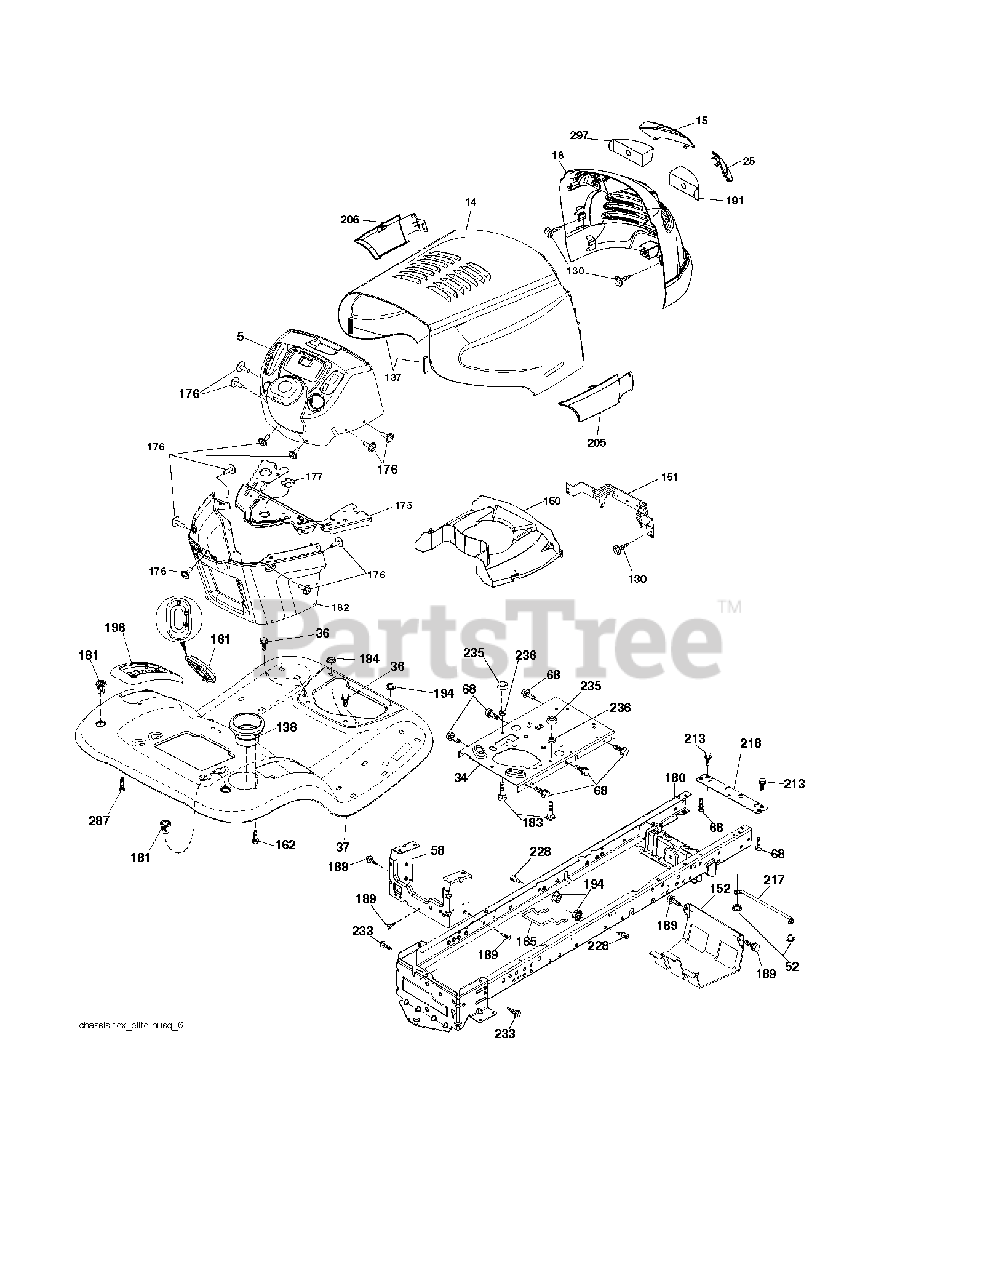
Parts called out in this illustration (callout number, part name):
14	HOOD.PNT.ELITE.TVENT.SVENT.SSK
18	GRILLE.ELITE HUSQ.BLACK.DL.
34	PLATE.ENGINE.WELDED.CHASSIS
36	SCREW 5/16"
52	LOCKNUT
58	DRAWBAR UPPER 2PC SMALL FENDER
68	SCREW LT
130	SCREW.#10 X 0.750.BOS (2 2)
137	BUMPER.HOOD.LARGE.1.75"
138	CUPHOLDER.TL.TEX.BLACK
152	SHIELD.BROWNING.W/TEX
161	WINDOW.FUEL.LT.TEX.BLACK
162	SCREW.HI-LO.CONSOLE
165	SUPPORT.TANK.REAR.W/TEX
175	CROSSMEMBER.LT
176	SCREW.#10-24X5/8.RN.QU
177	BUSHING,STEERING
180	CHASS.WLDMNT.TL.12GA/2P.48/54
181	FEND/FTRST.PCH.CPH.NFW
182	DASH.LOWER.LT.CCS
183	BOLT.5/16-18X1-1/4 FULL THD
189	SCREW
191	INSERT.REFLECTIVE.RH.
194	NUT LOCK HEX FLANGE 5/16-18
196	CONSOLE.ASM.DECKLFT.BL/RBT.TLT
205	SKIRT.SIDE.RH.ELITE.HUSQ.428
206	SKIRT.SIDE.LH.ELITE.HUSQ.BLACK
213	BOLT
217	ROD.PIVOT.HOOD
218	X-PIECE.HOOD.STOP.NON/
228	STUD.FASTNER.W/ANTI-ROTATE
233	BOLT.SHOULDER
235	SPACER FENDER
236	NUT.CENTERLOCK.5/16-
287	SCREW 1/4X20
297	INSERT LENS
